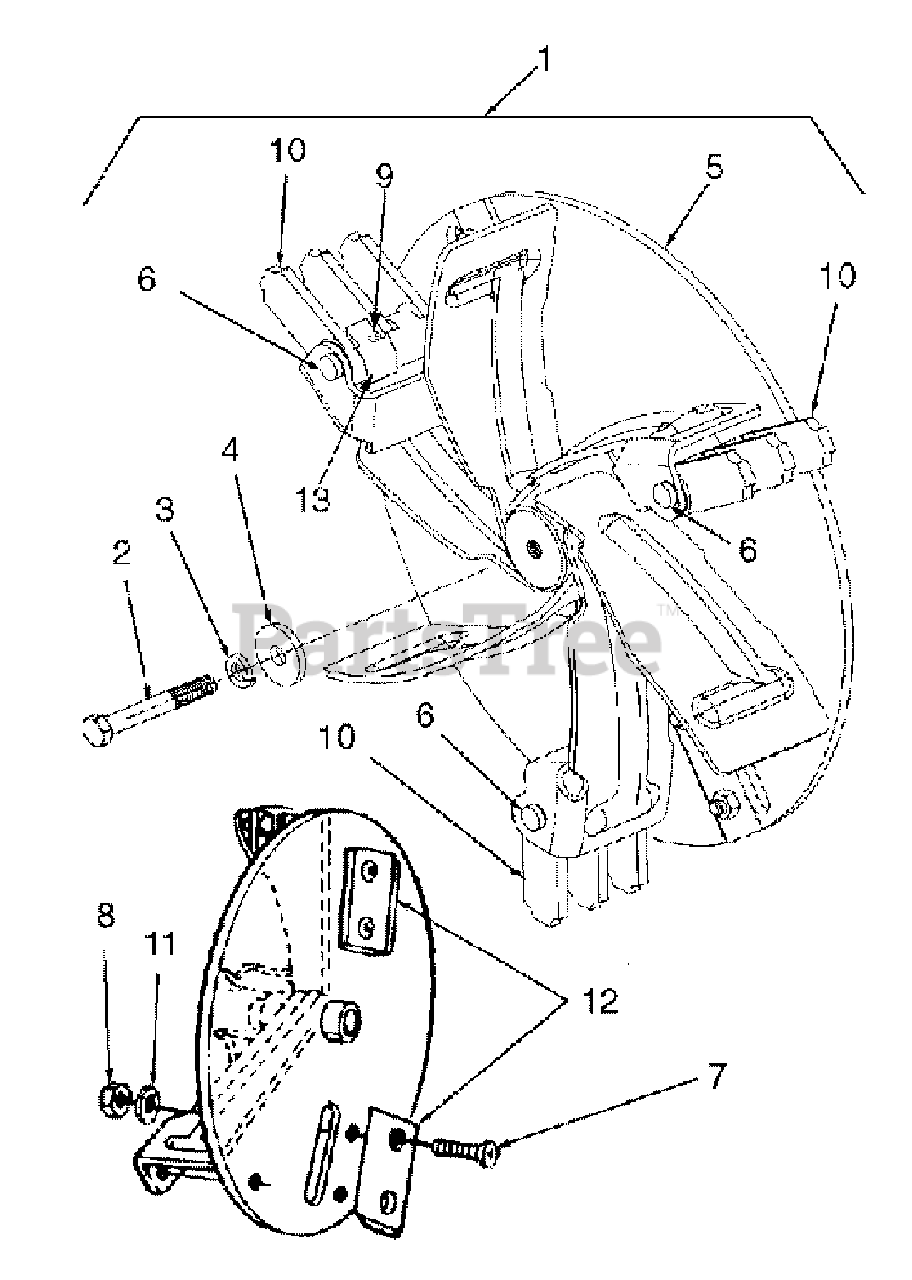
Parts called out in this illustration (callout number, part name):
1	Impeller Ass'y, Complete
2	Screw, Hex Cap, 3/8-24 x 2.75 GR5
3	Washer, Lock, 3/8 Heavy Duty 1
4	Washer, Flat, .406 x 1-1/4 HD1
5	Impeller Assembly
6	Pin, Clevis
7	Screw, Flat Hd. Cap, 5/16-24 x 1.0
8	Nut, Hex Insert Lock, 5/16-24
9	Pin, Spirol, 5/32 x 1.125
10	Blade, Flail
11	Washer, Lock, 5/16
12	Blade, Chipper
13	Pin Retaining Clip
